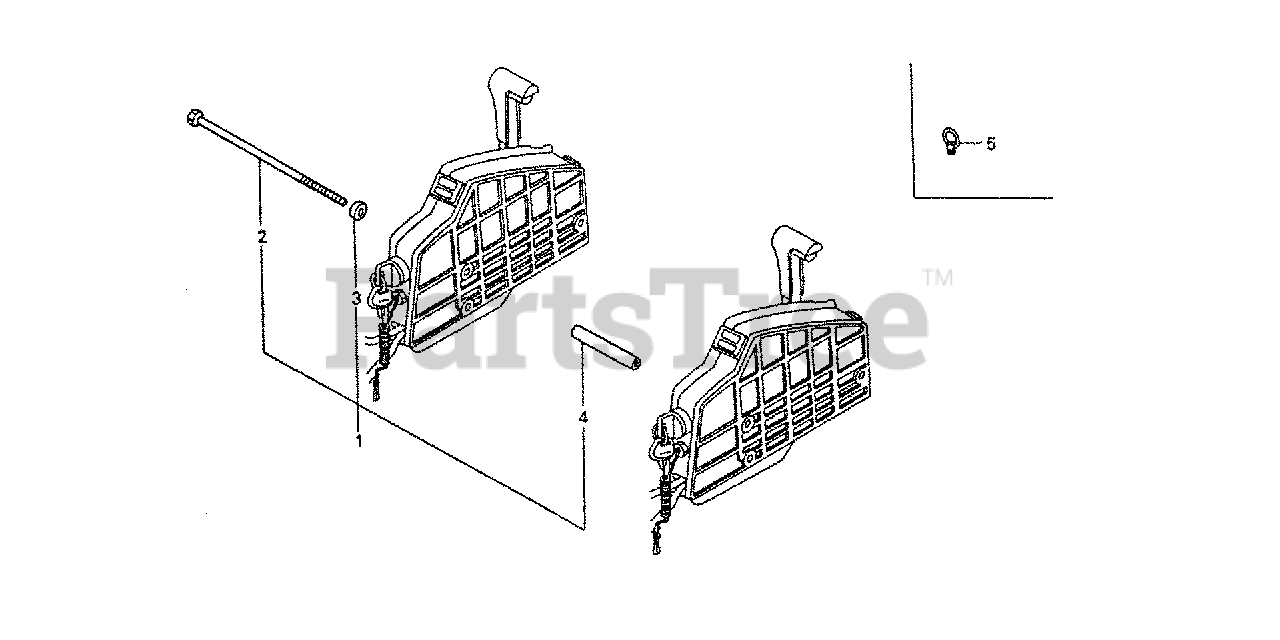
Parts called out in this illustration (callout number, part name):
1	BOLT KIT, SIDE REMOTE CONTROL
2	BOLT, SPECIAL (6X220)
3	COLLAR, DISTANCE (A)
4	COLLAR, DISTANCE (B)
5	EYE, LIFTING
